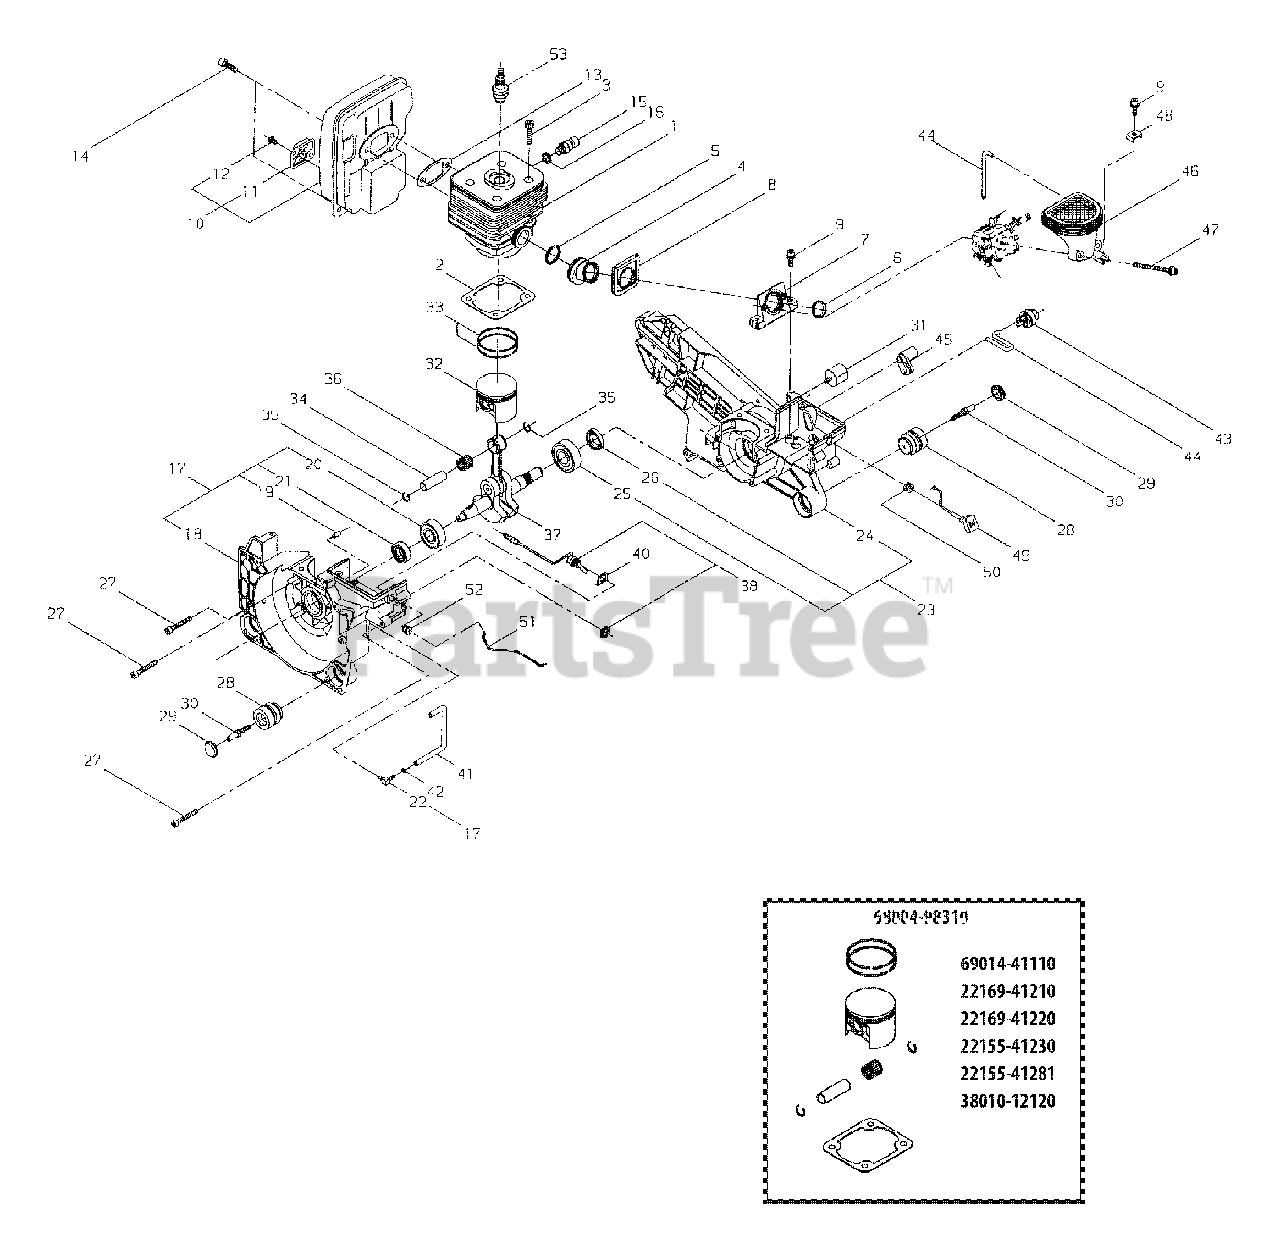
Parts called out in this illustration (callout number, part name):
1	CYLINDER
2	GASKET
3	BOLT 6
4	BOOT
5	SPRING, TENSION
6	SLEEVE 18
8	SEAL
9	BOLT, ADHESIVE M5×14
10	MUFFLER ASSY
11	TAIL PLATE
12	SCREW M5×8
13	GASKET
14	BOLT
15	VALVE, DECOMPRESSION
16	GASKET
17	CRANKCASE ASSY - LEFT
18	CRANKCASE ASSY - REAR
19	PIN, LOCATING 5×10
20	BEARING, BALL
21	SEAL, OIL 17
22	CONNECTOR, PIPE
23	CRANKCASE - RIGHT
24	CRANKCASE - RIGHT
25	BEARING, BALL 6203 C3
26	SEAL, OIL 17
27	BOLT M5×35
28	CUSHION 5
29	CAP, CUSHION
30	BOLT 5
31	CUSHION, AV 5
32	PISTON
33	RING, PISTON
34	PIN, PISTON 12
35	RING, SNAP
36	BEARING, NEEDLE 12
37	CRANKSHAFT ASSY
38	SWITCH ASSY
40	SWITCH PLATE
41	PIPE, PULSE
42	CLIP
43	BULB, PURGE
44	TUBE
45	GROMMET, CARBURETOR
46	ELBOW
49	ROD, CHOKE
50	GROMMET, CHOKE
51	ROD, THROTTLE
52	GROMMET
53	SPARK PLUG - BPMR7A
68004-98310	PISTON ASSY
